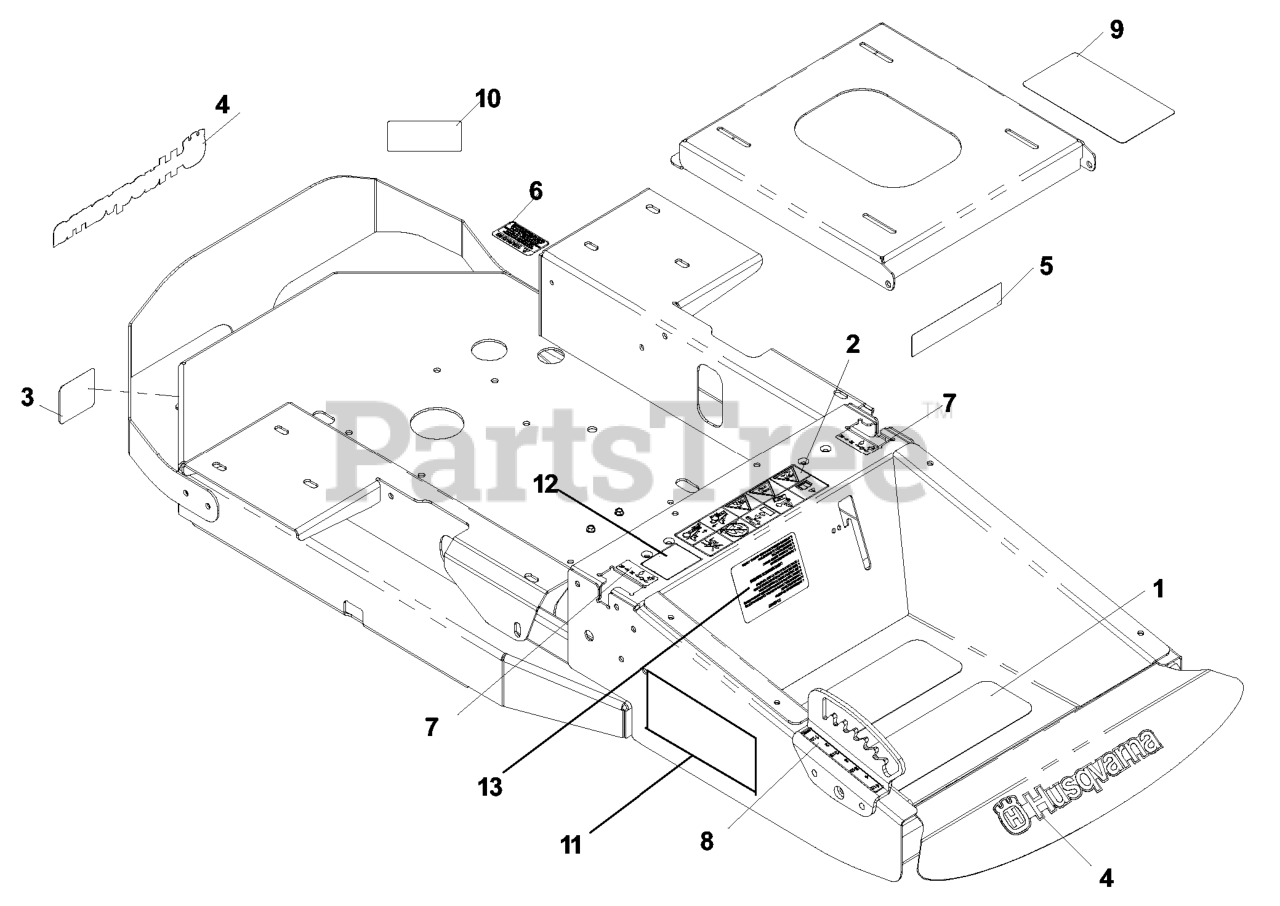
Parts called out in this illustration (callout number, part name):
1	ANTI-SKID PAD
2	DECAL, WARNING
3	DECAL, DO NOT TOW
4	DECAL, HUSQVARNA 12"
5	EURO DECAL-BATTERY WARNIN6
6	DECAL, PROP. 65
7	DECAL, MOTION CONTROL
8	DECAL, CUTTING HEIGHT
9	DECAL-SERVICE
10	DECAL, BELT DRIVE
11	DECAL, CZ4815
11	DECAL, CZ4817
12	DECAL, EXITING MOWER
13	DECAL, START
